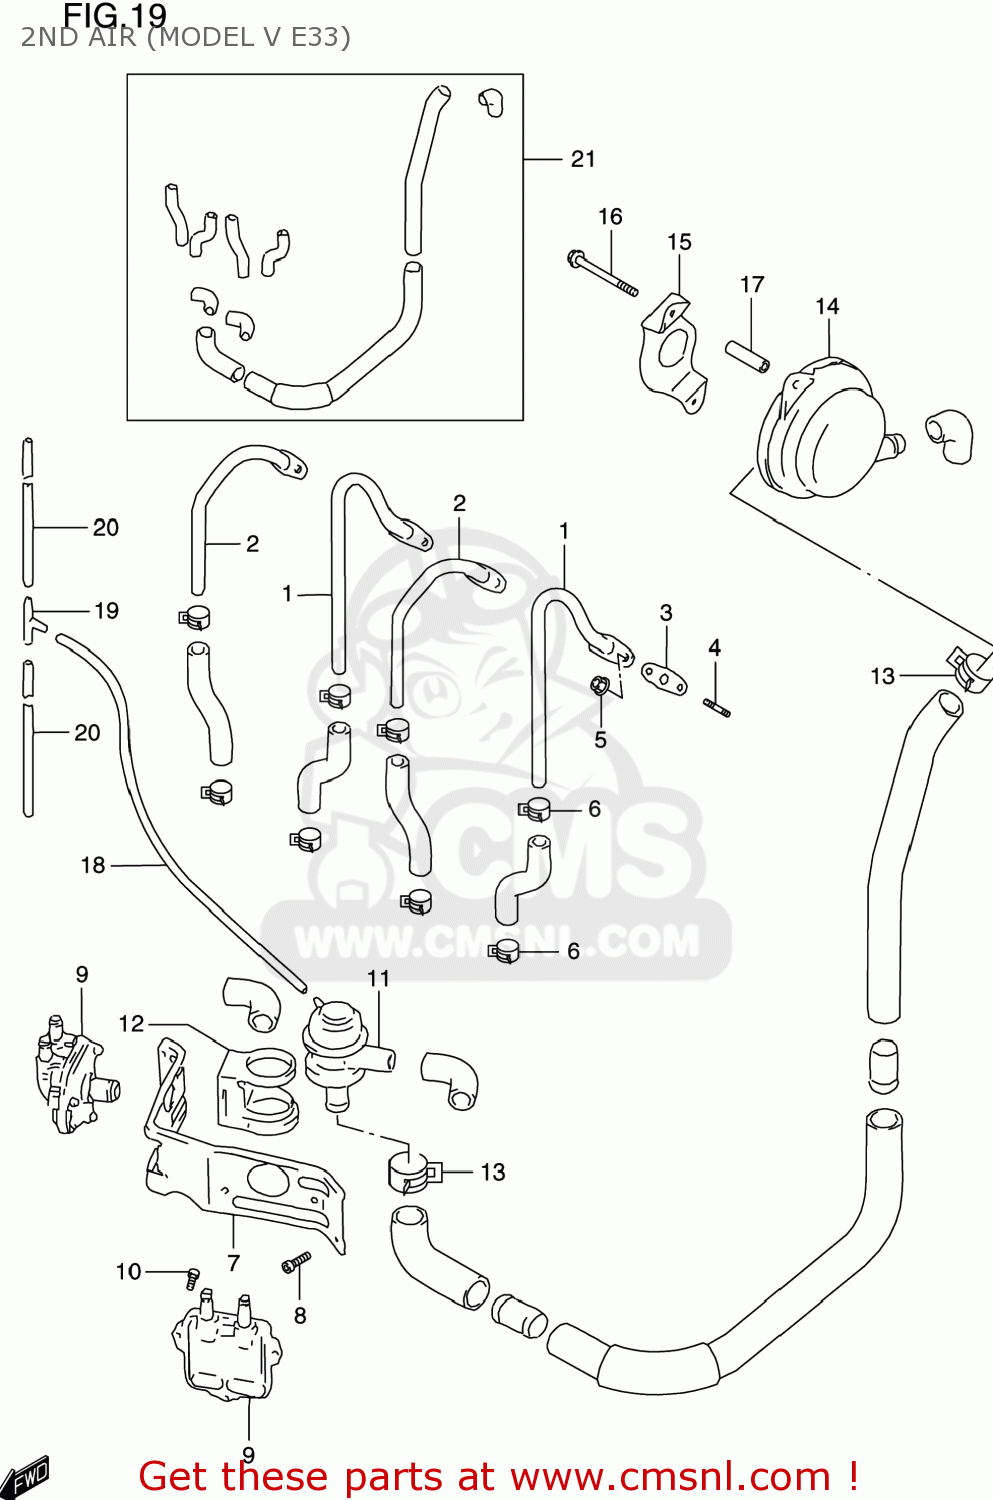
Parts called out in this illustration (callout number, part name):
1	PIPE COMP,SECOND AIR NO.1
2	PIPE COMP,SECOND AIR NO.2
3	GASKET,SECOND AIR PIPE (N (NAS)
4	STUD BOLT
5	NUT
6	CLIP
7	BRACKET COMP,SECOND AIR
8	BOLT 6X12
9	VALVE ASSY,2ND AIR REED
10	BOLT
11	VALVE ASSEMBLY,SECOND AIR SWITCH
12	CUSHION,2ND AIR VALVE
13	CLAMP
14	CLEANER ASSEMBLY,SECOND AIR
15	HOLDER,SECOND AIR CLEANER
16	BOLT
17	SPACER(6.5X10.5X40)
18	HOSE(4X7X600)
19	JOINT,3 WAY
20	HOSE(5X10X600)
21	HOSE SET,2ND AIR
